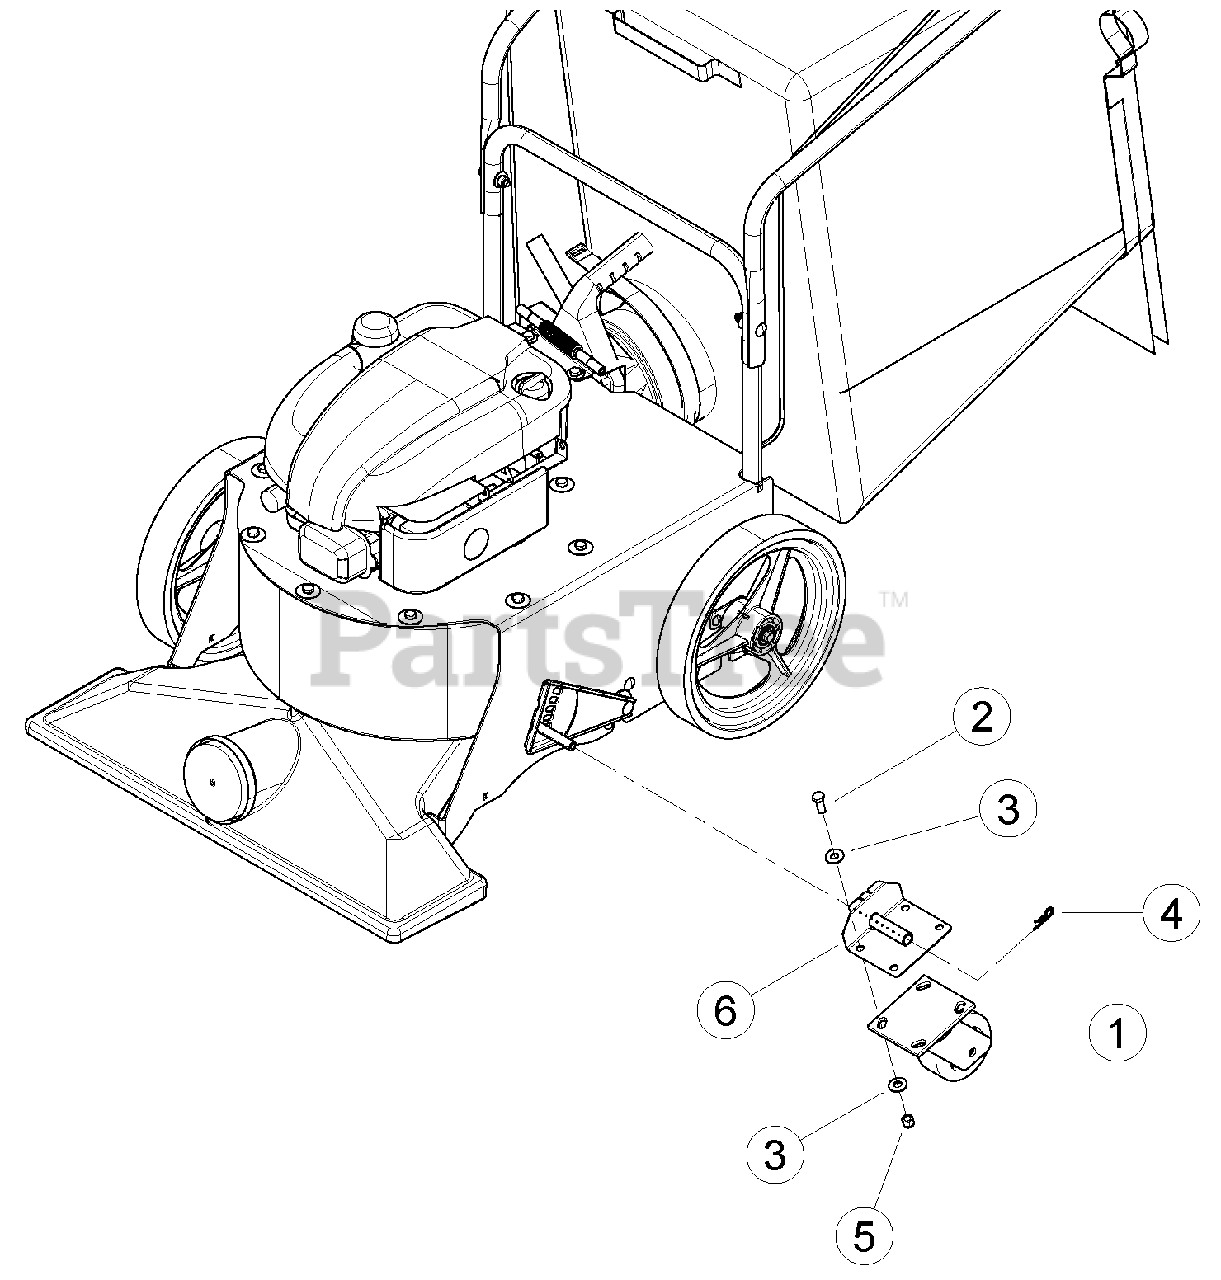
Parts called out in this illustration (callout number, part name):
1	WHEEL, 4 X 2 CASTER
2	BOLT, 3/8 X 1 GR5 HEX CAPSCREW ZP
3	WASHER, 3/8" FLAT ZP
4	HAIRPIN CLIP ZP #203
5	NUT, 3/8" NYL INSERT, NE, ZP
6	WELDMENT, CASTER WHEEL MOUNT
